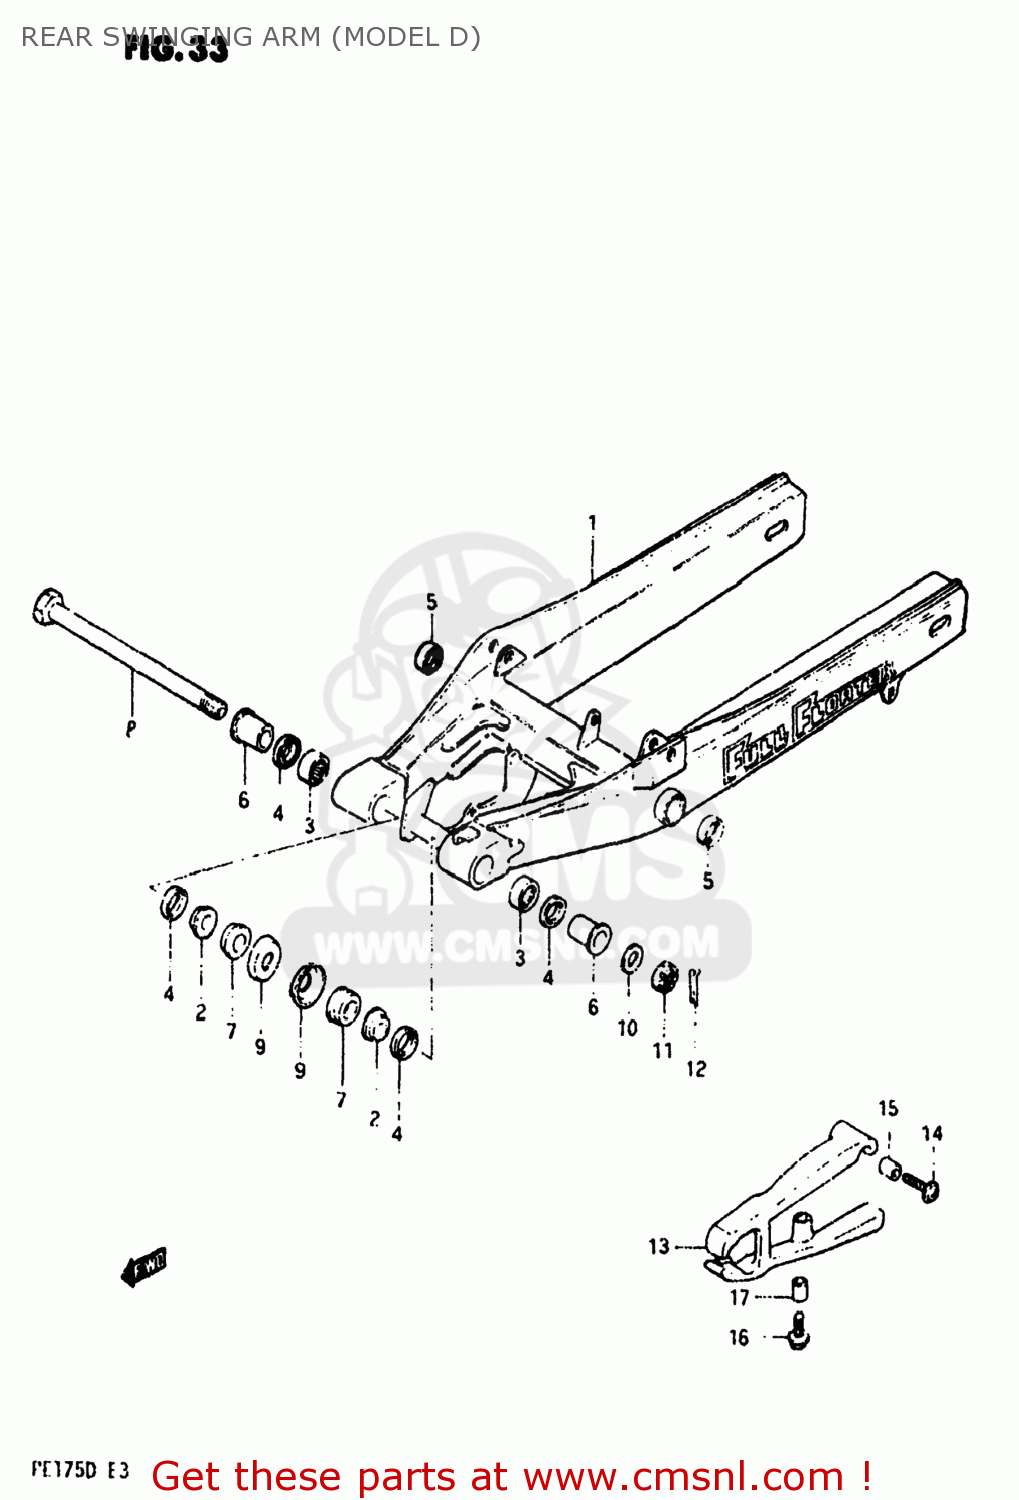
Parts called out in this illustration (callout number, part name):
1	SWING ARM ASSEMBLY,REAR
2	BUSH,RR SWINGINGARM PIVOT
3	BEARING(20X27X20)
4	OIL SEAL
5	OIL SEAL
6	SPACER,RR SWGARM PIVOT
7	SPACER,RR SWGARM PIVOT INNER
8	SHAFT,RR SWINGINGARM PIVOT
9	COVER,RR SWGARM DUST SEAL
10	WASHER
11	NUT 14MM
12	COTTER PIN
13	BUFFER,CHAIN TOUCH DEFENSE
14	BOLT,CHAIN TOUCH DEFEND
15	SPACER (6.1X9X9)
16	BOLT,CHAIN TOUCH DEFEND
17	SPACER(6.5X10.5X22.5)
